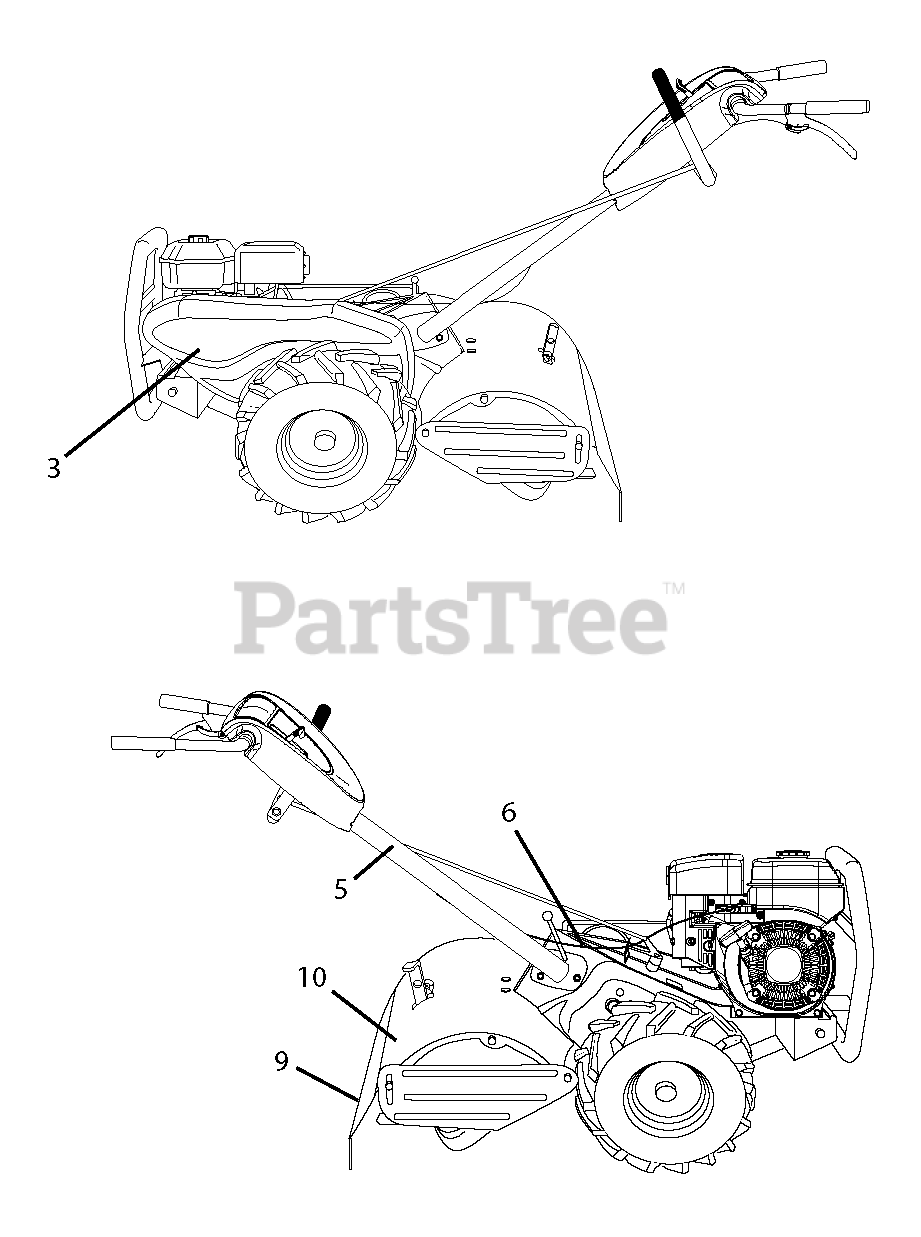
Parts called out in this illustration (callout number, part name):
3	RP.DECAL.BADGE.170MM.TEXTLOGO
5	DECAL.PLACEMENT.HAND.SYMBOLS
6	DECAL.SHIFT.INDICATOR.TILLER
9	DECAL.WARNING.4-SYM.TILLER.INT
10	DECAL EUROPE STANDARD CE
